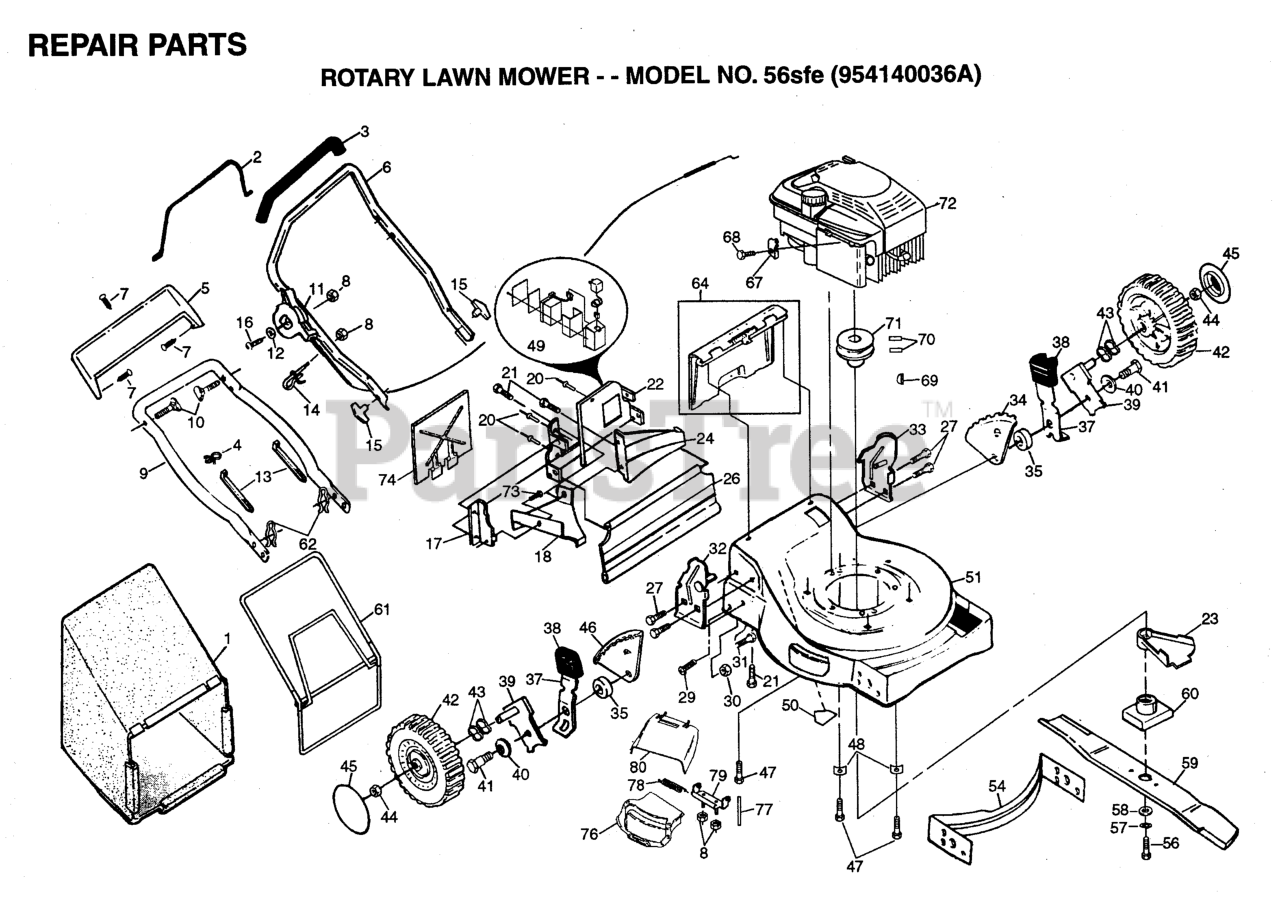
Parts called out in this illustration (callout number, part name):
1	GRASS BAG
2	CONTROL BAR
3	HANDLE GRIP
4	CLIP CABLE SNAP
5	TRIM PLATE
6	UPPER HANDLE
8	NUT
9	HANDLE, LOWER
10	HANDLE BOLT
11	THROTTLE CONTROL
13	TIE GUIDE
14	ROPE GUIDE
15	HANDLE KNOB
17	SIDE BAFFLE
18	DISCHARGE BAFFLE
20	RIVET BLIND
22	BACK PLATE
23	DEBRIS SHIELD
24	REAR BAFFLE
26	REAR SKIRT
27	SELF-TAPPING SCREW 5/16-18X3/4
29	HINGE SCREW
30	LOCKNUT PM
32	HANDLE BRACKET ASSEMBLY-RIGHT
33	HANDLE BRACKET ASSEMBLY - LEFT
34	WHEEL ADJ BRKT RF-LR
35	RP SPACER HT ADJ
37	SELECTOR SPRING
38	SELECTOR KNOB
39	AXLE ARM
40	WASHER.BELLEVILLE (3 2 LB)
41	BOLT
42	WHEEL.8X2.PR.LP.RAD.GREY
43	WAVE WASHER
44	HEX FLANGE LOCKNT
45	HUBCAP.8".GREY
46	WHEEL ADJ BRKT RR-LF
47	BOLT 3/8-16X1-1/8
48	WASHER.ENGINE.BZP
50	DECAL HYT
54	FRONT BAFFLE
56	SCREW, HEX HD 3/8-24 X 1-3/8
57	LOCKWASHER
58	WASHER,HARDEN
60	BLADE ADAPTOR
61	CATCHER.FRAME.WALK
62	HAIRPIN COTTER
64	REAR DOOR ASSEMBLY
68	SCREW.HEX.HEAD.WASHER.10-16
69	HI PRO KEY PM WSL
71	ENGINE.PULLEY.FWG
73	SCREW.HXTAP.10-24
74	MULCHER PLATE
77	ROD.HINGE.COMBI-C
78	SPRING HINGE
79	BRACKET.HINGE ASM.W/FIN
